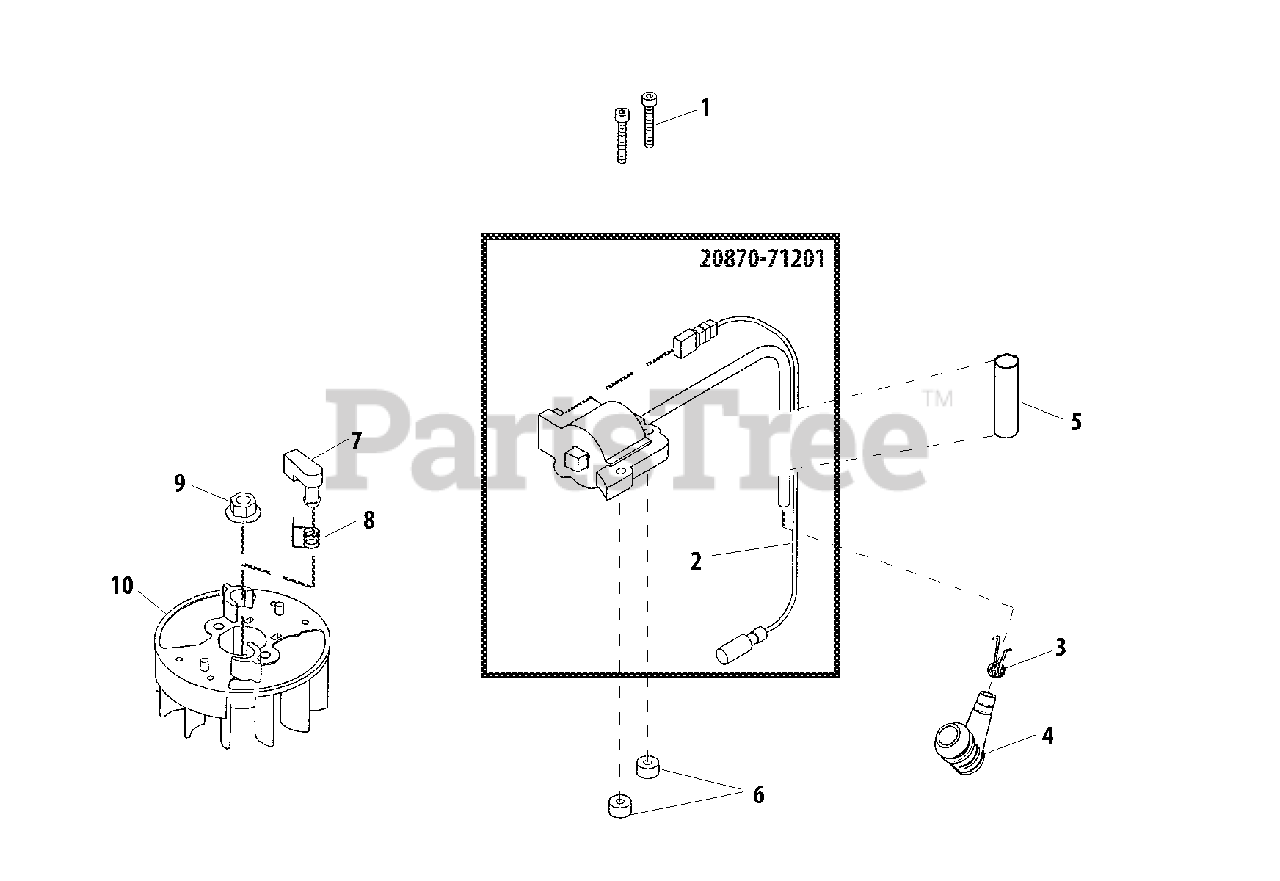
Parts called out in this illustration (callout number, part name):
1	SCREW - 4X26
2	WIRE
3	TERMINAL, SPARK PLUG CAP
4	CAP, SPARK PLUG
5	TUBE
6	INSULATOR
7	PAWL, STARTER
8	SPRING
9	NUT - 8
10	FLYWHEEL
20870-71201	IGNITION COIL ASSY
